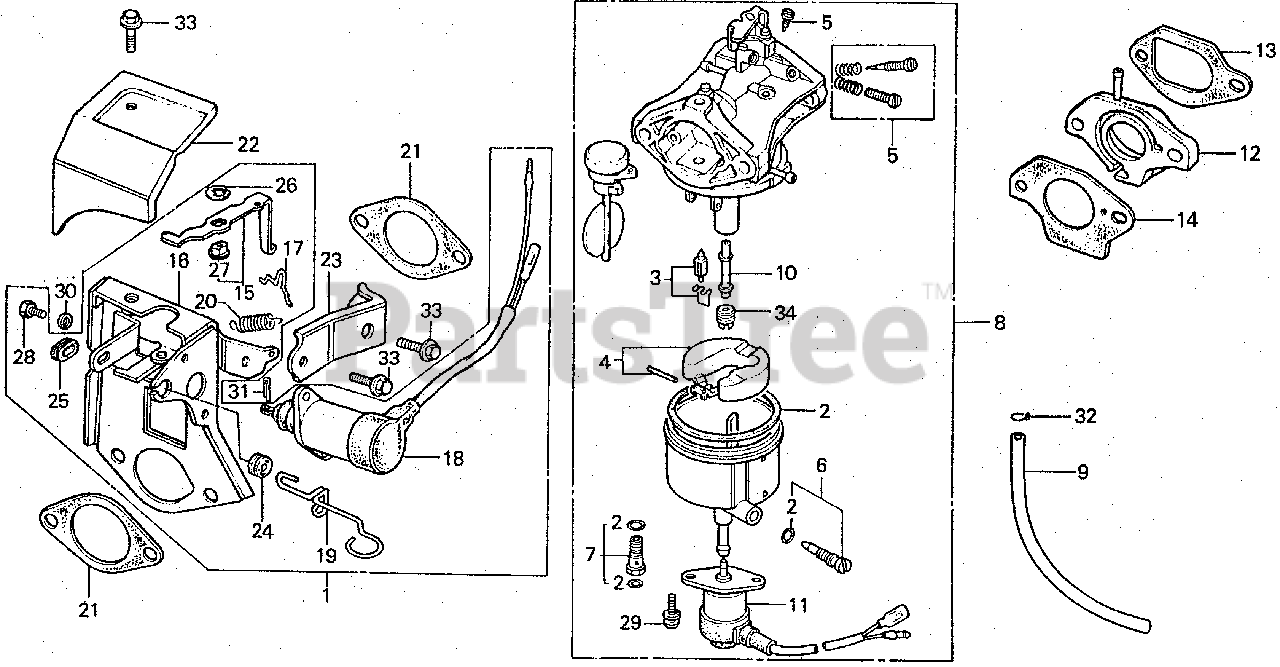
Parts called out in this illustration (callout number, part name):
2	GASKET SET
3	VALVE SET, FLOAT
5	SCREW SET A
6	SCREW SET, DRAIN
7	SCREW SET
7	SCREW SET B (NOT AVAILABLE)
7	SCREW SET B
8	CARBURETOR ASSY. (BB37A A) (NOT AVAILABLE)
8	CARBURETOR ASSY. (BB37A B) (NOT AVAILABLE)
8	CARBURETOR ASSY. (BB37B A) (NOT AVAILABLE)
8	CARBURETOR ASSY. (BB37B B) (NOT AVAILABLE)
9	TUBE, DRAIN
10	NOZZLE, MAIN (NOT AVAILABLE)
10	NOZZLE, MAIN
11	VALVE ASSY., SOLENOID (NOT AVAILABLE)
11	VALVE ASSY., SOLENOID
12	INSULATOR, CARBURETOR (NOT AVAILABLE)
13	GASKET, INSULATOR
14	GASKET, CARBURETOR
16	STAY SET, SOLENOID
16	STAY, SOLENOID
17	ROD, CHOKE (NOT AVAILABLE)
18	CHOKE, SOLENOID
18	CHOKE, SOLENOID (N/A: USE ALTERNATE P/N 06162-ZA0-315)
19	ROD, MANUAL CHOKE (NOT AVAILABLE)
20	SPRING, CHOKE RETURN
21	GASKET, AIR CLEANER
22	COVER, SOLENOID
23	BRACKET, CHOKE STAY
24	GROMMET, CHOKE ROD
25	GUIDE, CHOKE ROD
28	BOLT, HEX. (5X8)
29	SCREW-WASHER (5X12)
30	WASHER, SPRING (5MM)
31	PIN, COTTER (1.6X25)
31	PIN, SPLIT (2.0X15)
32	CLIP, TUBE (C9)
33	BOLT, FLANGE (6X12)
34	JET, MAIN (#90)
34	JET, MAIN (#98)
34	JET, MAIN (#100)
34	JET, MAIN (#102)
34	JET, MAIN (#82)
34	JET, MAIN (#85)
34	JET, MAIN (#88)
34	JET, MAIN (#92)
34	JET, MAIN (#92) Use from Engine SN BB37B A.
